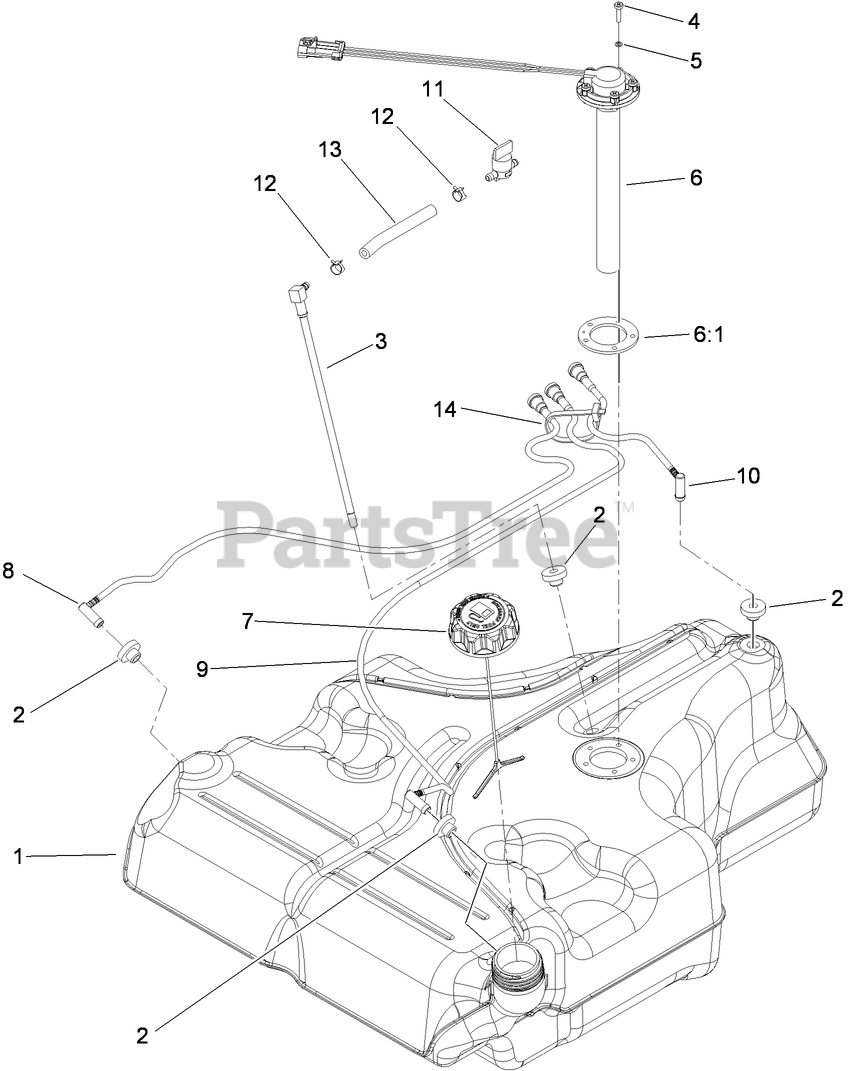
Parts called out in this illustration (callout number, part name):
1	TANK, LOW PERM FUEL
2	BUSHING
3	FUEL LINE KIT (WITH GROMMET)
4	SCREW-PAN
5	WASHER-LOCK
6	SENDER-LEVEL, FUEL
6:1	GASKET-SENDER, FUEL
7	CAP-FUEL, RATCHETING
8	RH VENT LINE KIT (WITH GROMMET)
9	LH VENT LINE KIT (WITH GROMMET)
10	REAR VENT LINE KIT (WITH GROMMET)
11	VALVE-FUEL
12	CLAMP-HOSE
13	HOSE-FUEL
14	TIE-PLASTIC
